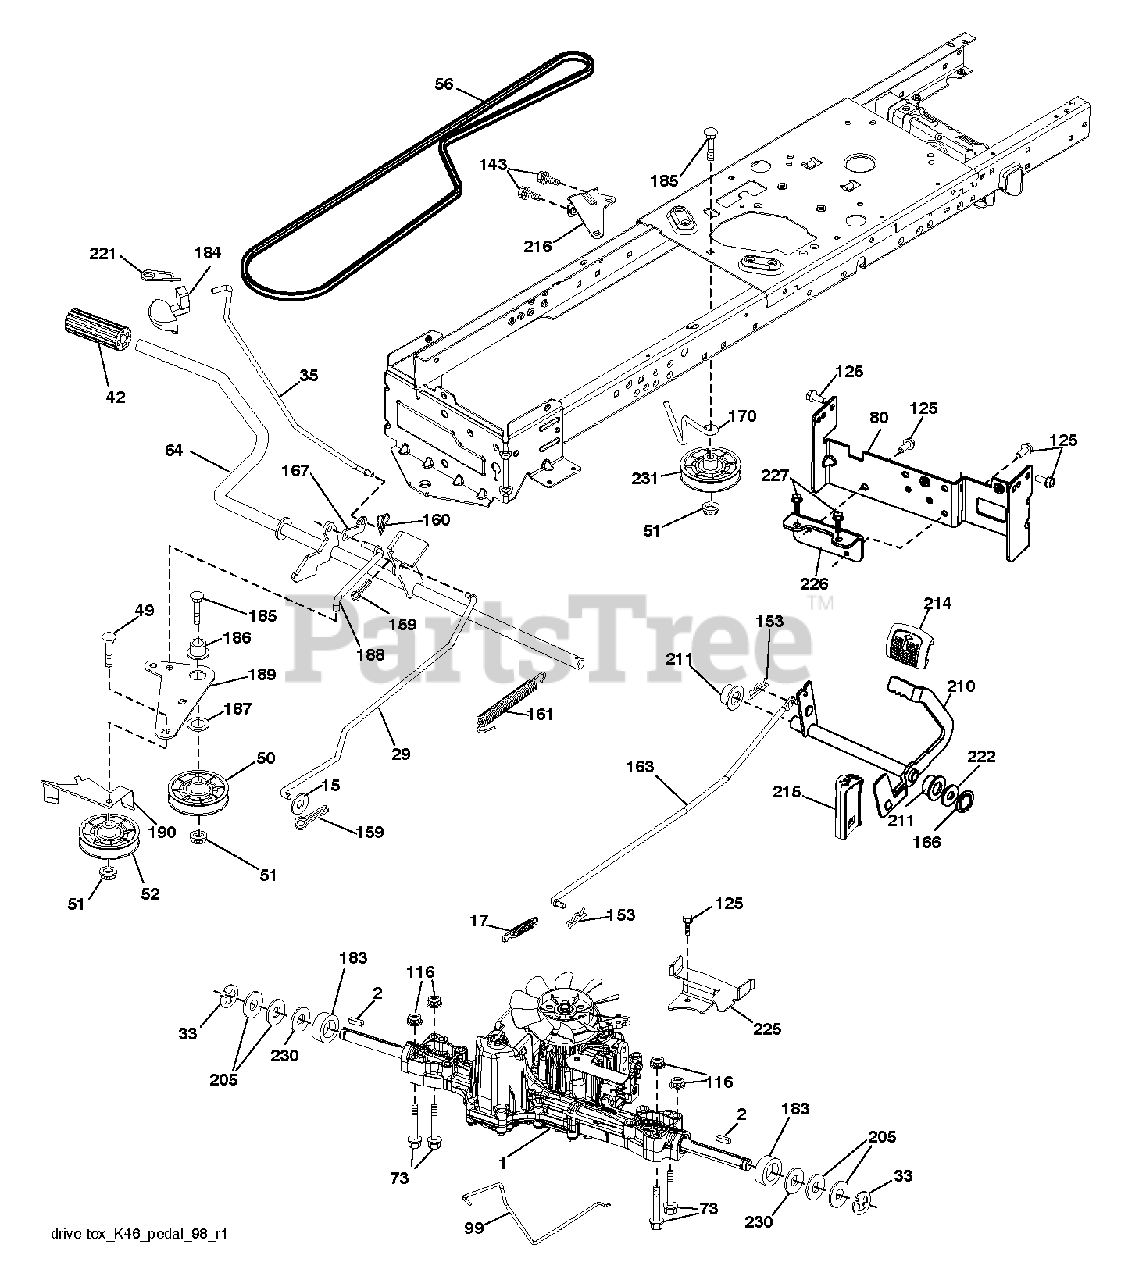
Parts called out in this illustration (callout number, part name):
2	SQUARE KEY
15	WASHER
17	SPRING.BRAKE.K46.GREEN
29	ROD.BRAKE.K46
33	E-RING LT
50	IDLER.FLAT.910.OFFSET
52	IDLER.V-GROOVE.910.OFFSET
64	SHAFT.ASM.PEDAL.BRK.CNTR
80	STRAP.TORQUE.K46.K57R.TT
99	ROD.SPRING.BYPASS.K46.LT.Z
116	NUT LOCK HEX FLANGE 5/16-18
143	SCREW LT
159	COTTER PIN
160	RETAINER CLIP
161	SPRING, RETURN LT
166	NUT.PUSH.625
167	LATCH.BRAKE.SPRING
170	KEEPER.CENTER SPAN.1.688
183	SPACER AXLE
186	SPACER.RETAINER
188	LINK.CLUTCH.GROUND.DRIVE
189	BELLCRANK.GROUND.DRIVE.TEX.
190	KEEPER.BELLCRANK.DRIVE
210	ROCKER.ASM.PEDAL.CONTR
211	BEARING.NYLON
214	PAD PEDAL FORWARD
215	PEDAL.REVERSE.TEX.GT.4
216	BRACKET.PULLEY.IDLER.W/TEX
221	RETAINER.SPRING.CLIP.H
222	WASHER 21/32 X 1-1/4 X 10 GA.
225	KEEPER.BELT.TRANSAXLE.K46
226	BRACKET.MOUNT.TORQUE.K46.TLT
230	WASHER.HARDENED
231	IDLER.V-GROOVE.1.688.OFFSET
